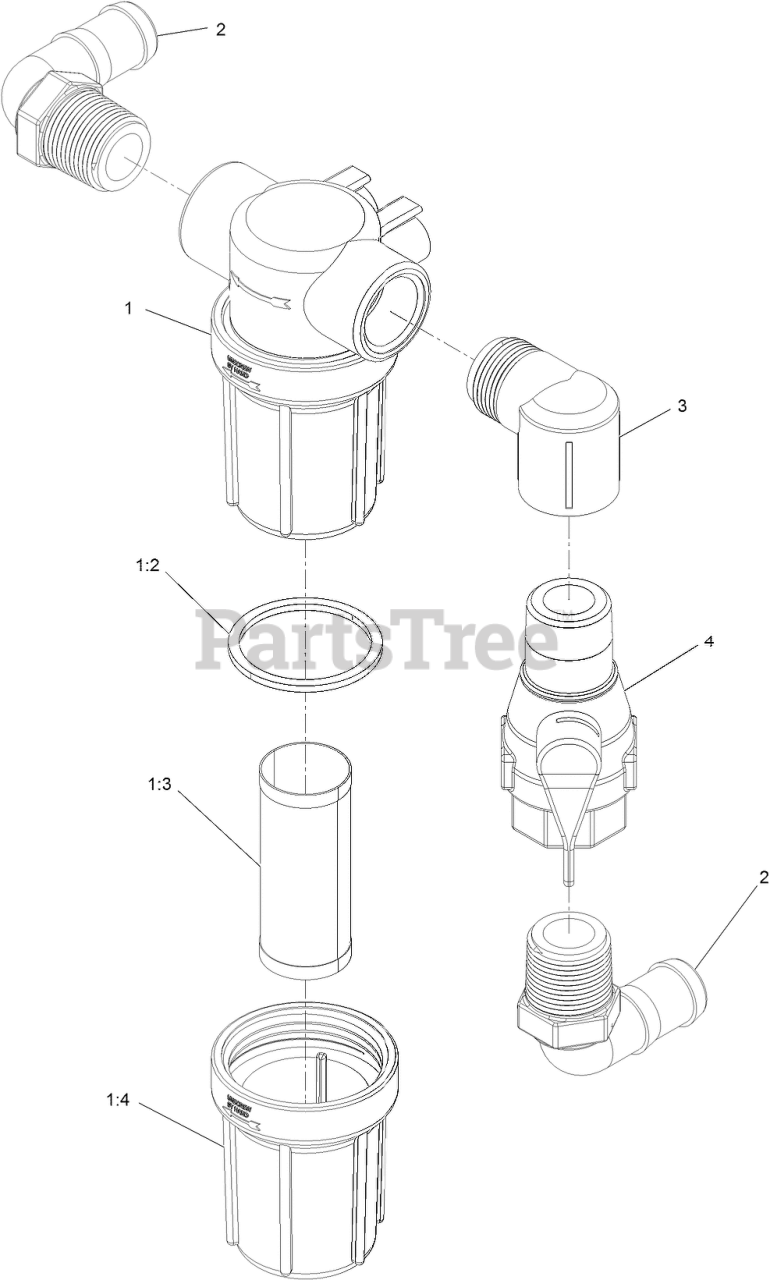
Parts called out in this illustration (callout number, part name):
1	STRAINER-LINE
1:2	GASKET-HEAD, LINE STRAINE
1:3	SCREEN-STRAINER, 30 MESH
1:4	BOWL-STRAINER
2	ELBOW-HOSEBARB
4	VALVE-BALL
